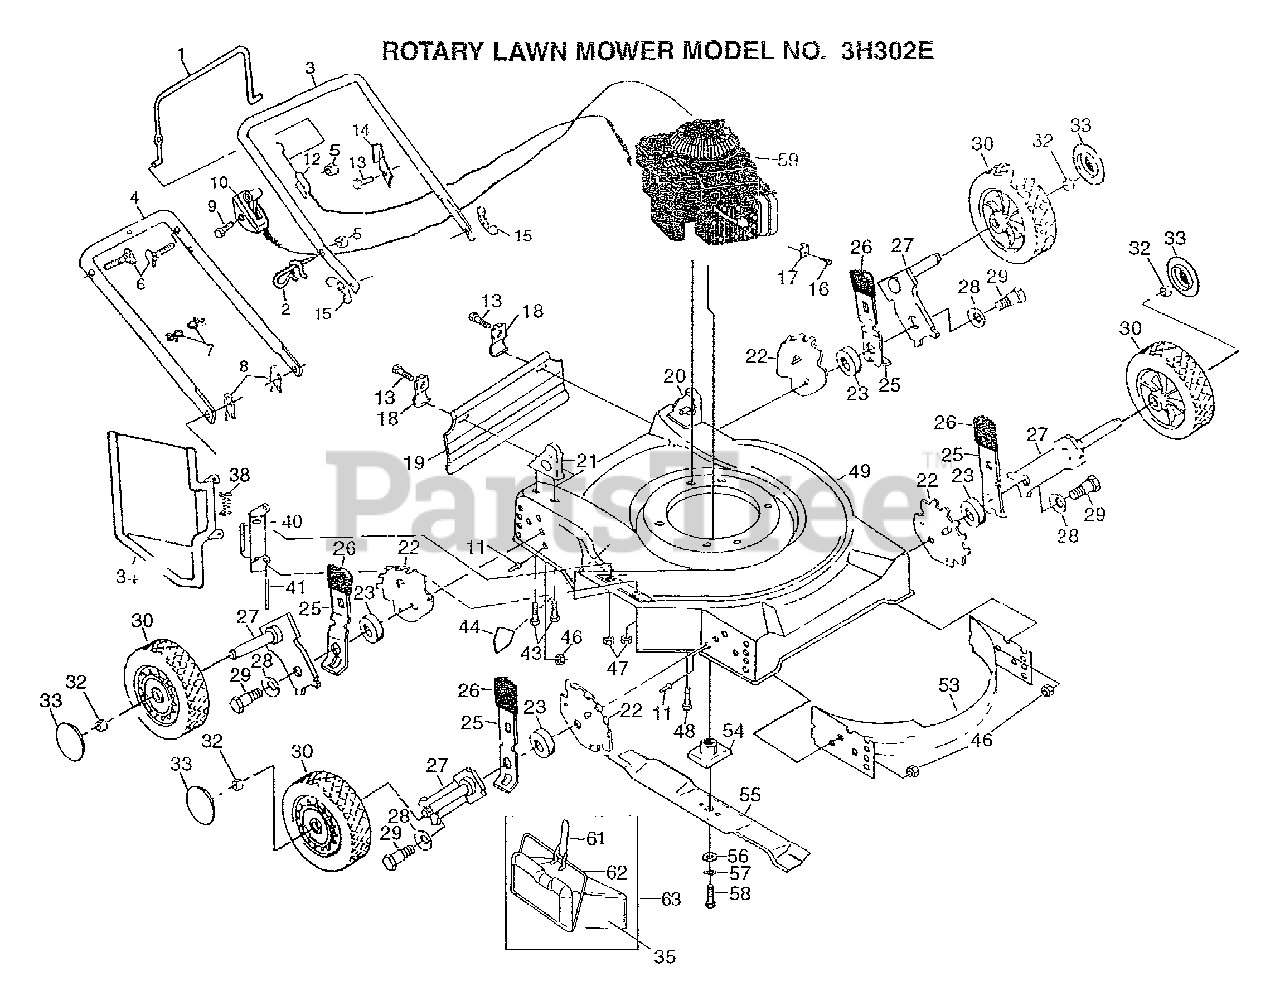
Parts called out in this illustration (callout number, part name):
1	CONTROL BAR
2	ROPE GUIDE
4	LOWER HANDLE
6	BOLT.HANDLE.LM
8	HAIRPIN COTTER
9	SCREW.HXHD.WASH.
10	"CONTROL, THROTTLE"
11	BLIND RIVET
12	"CABLE,ENG ZONE CO"
13	TAPPING SCREW
14	"BRKT,UPSTOP"
15	"NUT,WING PM"
16	SCREW PM
17	CABLE CLAMP
18	"BRKT,DEFL PM"
19	SKIRT.REAR.FGD.22
20	HDLE BRKT ASSY LH
21	HDLE BRKT ASSY.RH
22	BRACKET.ADJ.9POS.
23	SPACER.HEIGHT.ADJ
25	SPRING SELECTOR
26	KNOB PM
27	ARM.AXLE.ASM.BZP.
28	"WASHER, BELLEVIL."
29	BOLT SHLD 3/8-16
30	WHEEL.8X1.75.WHT
32	HEX FLANGE LOCKNT
33	HUB CAP
34	GUARD.DISCH.22SD.
35	MULCHER PLUG
38	SPRING.HINGE
40	BRACKET.HINGE.W/F
41	ROD.HINGE.COMBI-C
43	SCREW 5/16-18X3/4
44	DECAL HYT
46	LOCKNUT PM
48	BOLT.ENG.3/8-16
49	KIT.HSG.22SD.PUSH
53	BAFFLE.FRT/REAR
54	BLADE ADAPTOR
55	"BLADE.MULCH.22"""
56	"WASHER,HARDEN"
57	LOCKWASHER
58	SCREW
61	LATCH.BAIL.MULCH.
62	MULCHER BAIL
63	"MULCH,PLUG,22SD"
